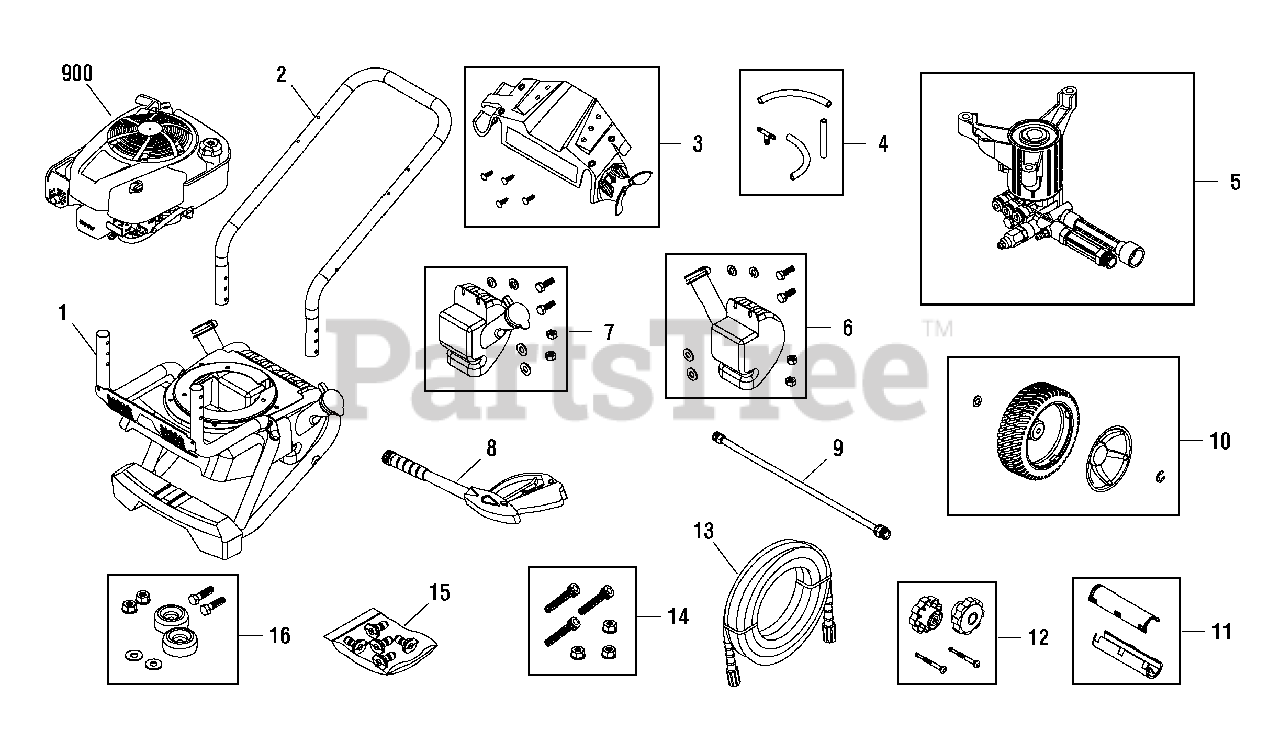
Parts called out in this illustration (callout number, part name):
5	PUMP
8	GUN
9	EXTENSION, QC
12	KIT, Hardware, Handle
14	KIT, Hardware, Pump Mounting
15	KIT, QC Nozzles
16	MOUNT, Vibration
900	* ENGINE
